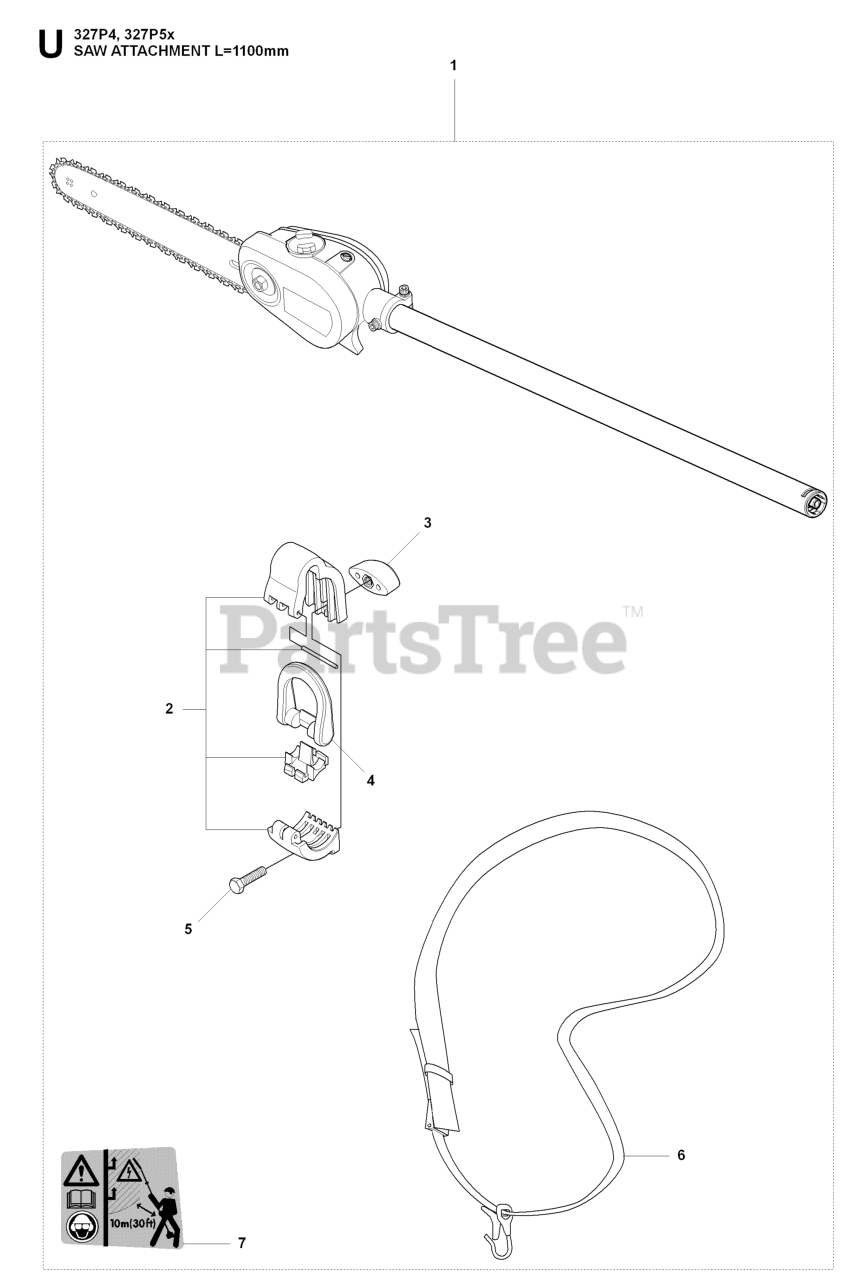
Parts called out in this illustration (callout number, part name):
1	Dx Pole Saw Attachment
2	HANGING BRACKET
5	SCREW M6S 5X20
6	Harness-w/o warning
7	DECAL
